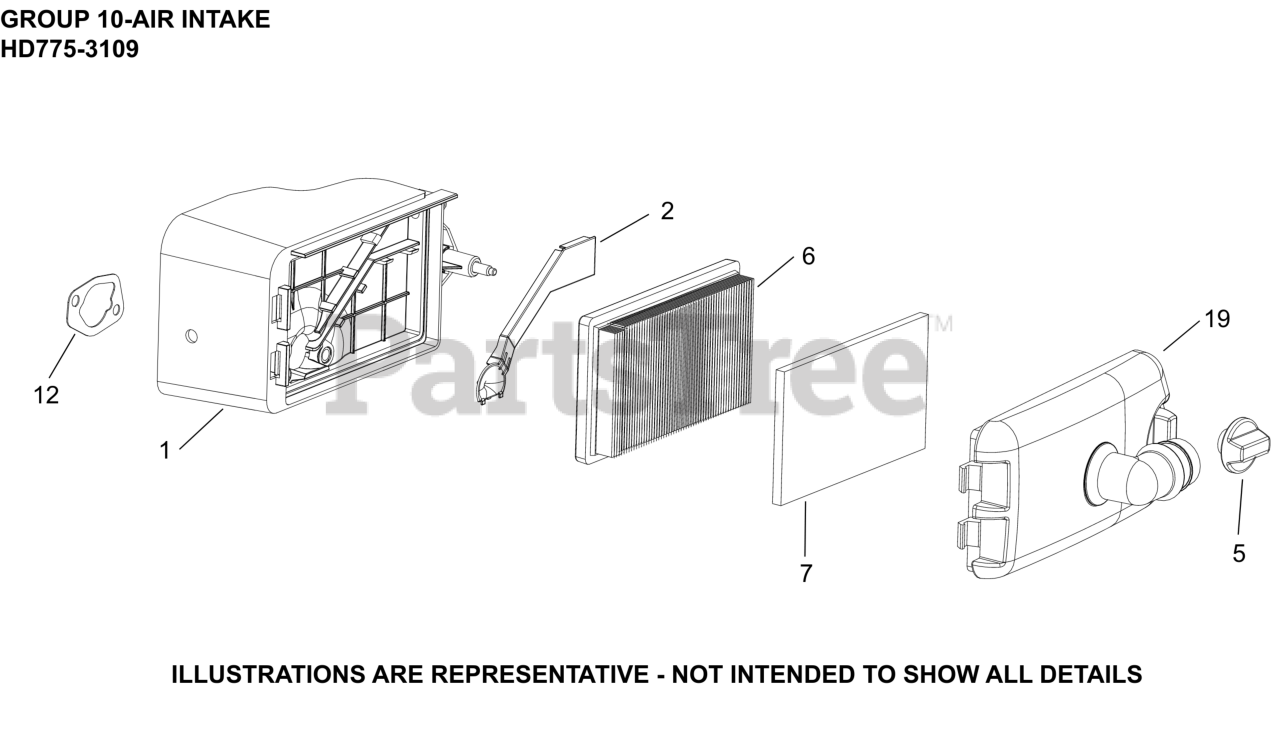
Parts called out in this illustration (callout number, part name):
1	AIR CLEANER BASE-USE 14 094 23-S
2	COVER, A/C BASE (BREATHER GAS)
5	KNOB-USE 14 341 07-S
6	ELEMENT, AIR FILTER
7	ELEMENT, PRE-CLEANER
12	GASKET, AIR CLEANER BASE
19	COVER ASSEMBLY, AIR CLEANER (SERVICE)
